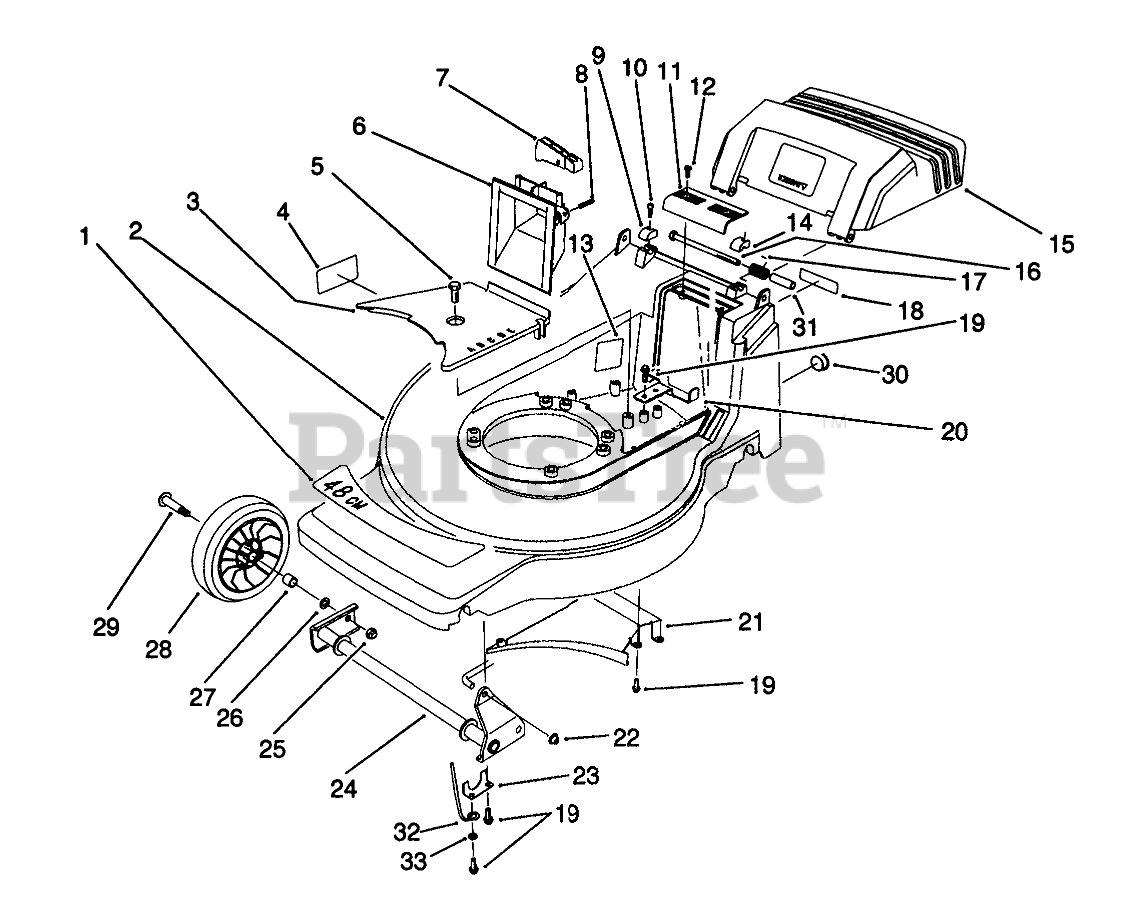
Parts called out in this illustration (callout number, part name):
1	DECAL - DECK
2	Housing-48cm (Incl. Ref. #1, 4, & 13)
3	BELT COVER
4	Decal Danger
5	SCREW-HWHTF
6	GRIP - LOWER
7	TRIGGER - HOC
8	PIN-SPIRAL
9	CAP-HINGE BOLT, RH
10	SCREW-HSH
11	GRIP-UPPER
12	SCREW-PPH, PLASTITE
13	Decal-Noise
14	CAP-HINGE BOLT, LH
15	Door-Discharge
16	SCREW-HH
17	DOOR SPRING
18	DECAL FRENCH REGUL.
19	SCREW-HWHTF
20	REAR BELT GUIDE
21	Ramp-Discharge
22	NUT-PUSH
23	FRONT SECURING PLATE
24	FRONT PIVOT WA
25	Nut
26	WASHER
27	BUSHING
28	Wheel & Tire Assembly (Incl. Ref. #28)
29	BOLT-WHEEL
30	DOME PLUG (DP-1000)
31	SPACER-DOOR
32	LH AXLE RETAINER
33	WASHER-FLAT
